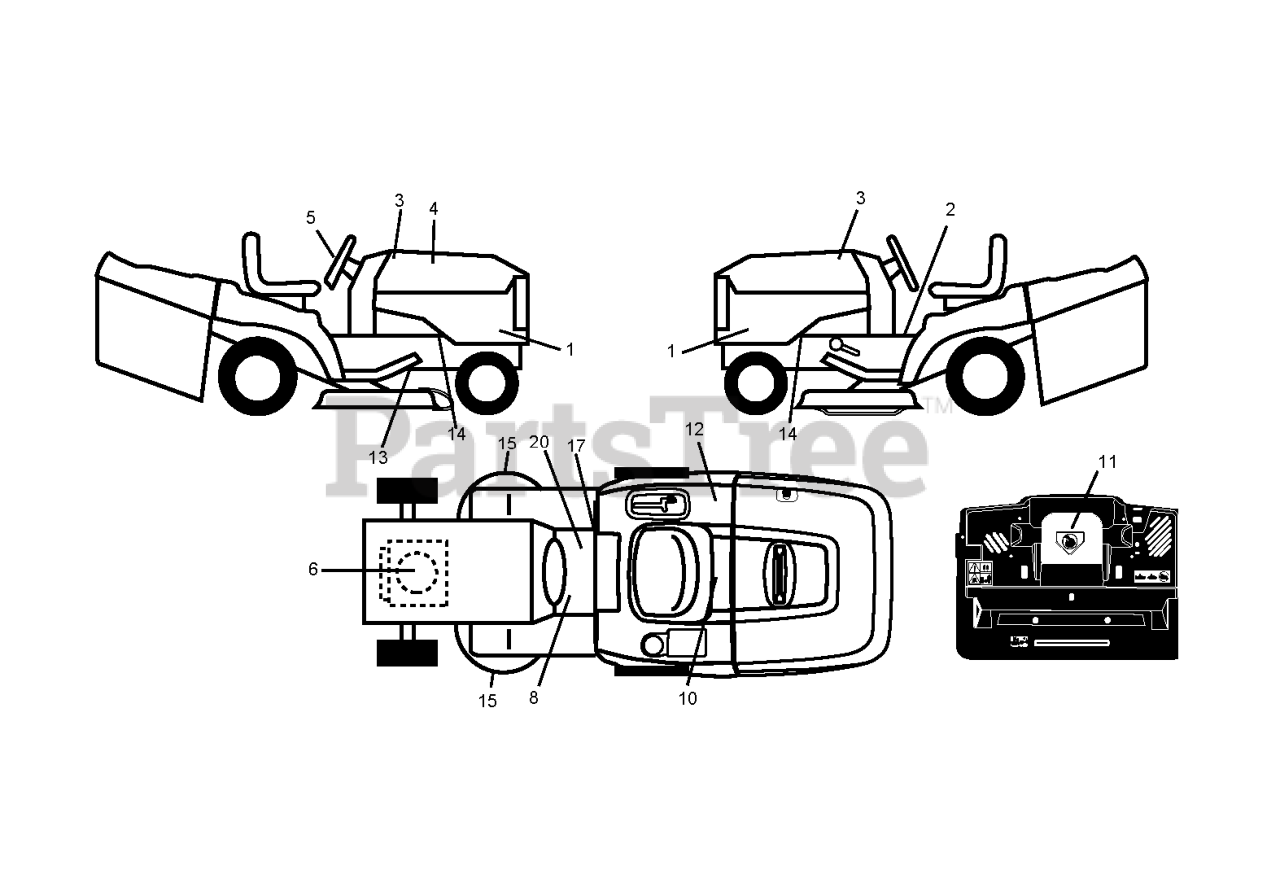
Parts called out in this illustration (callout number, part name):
1	DECAL PANEL
2	LABEL
3	DECAL.HOOD.NAMELOGO.HUSQ
5	DECAL.WHEEL.STRG.LGN.H
6	DECAL
8	DECAL
10	DECAL BTRY SYMBOLS
11	DECAL.INTERNATIONL.CUTFINGER
12	Decal, Fender 100 DB/CE
17	DECAL PARK BRAKE
20	DECAL.BYPASS.FENDER.CRD.LT.YT
